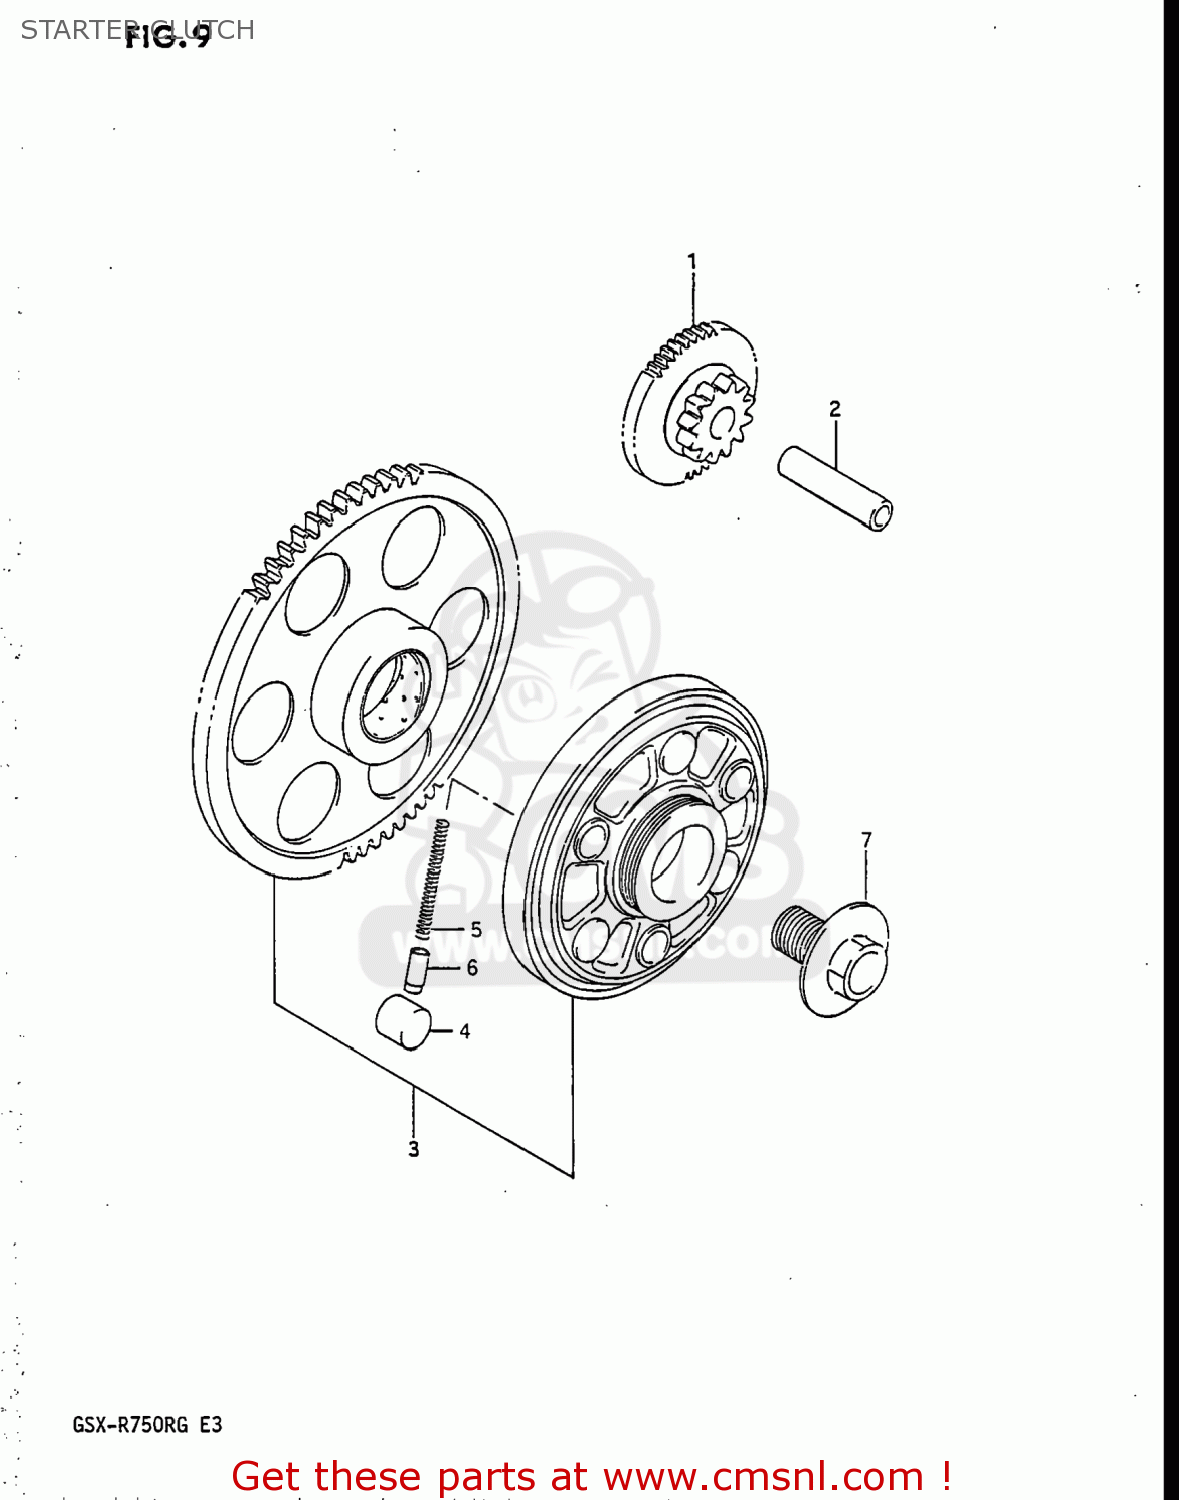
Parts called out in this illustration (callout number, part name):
1	GEAR,STARTER IDLE
2	PIN(7X11X42)
3	CLUTCH SET,STARTER
4	PIN(14X13)
5	SPRING
6	PIECE,PUSH
7	BOLT(14X21)
